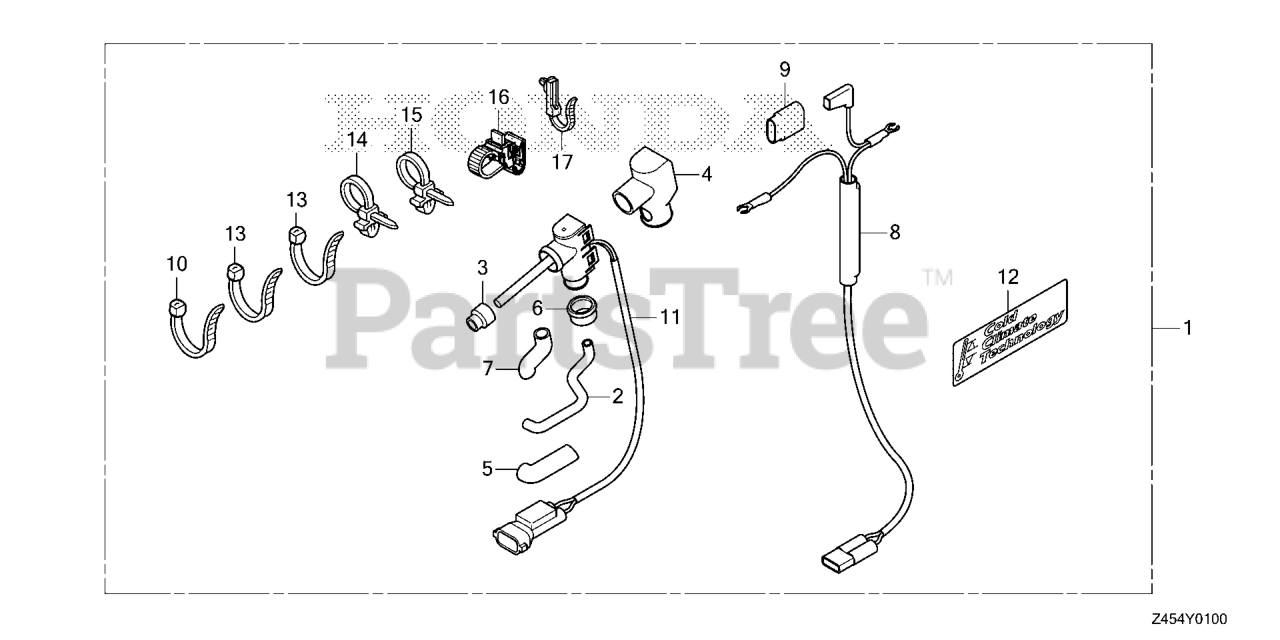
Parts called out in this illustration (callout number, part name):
1	KIT, BREATHER HEATER
2	TUBE, BREATHER
3	TUBE B, BREATHER
4	INSULATOR
5	INSULATOR A
6	TUBE C, BREATHER
7	INSULATOR B
8	SUB-WIRE ASSY.
9	TUBE, PVC (16X30)
10	TIE, CABLE (C)
11	HEATER, BREATHER L
12	MARK (CCT)
13	BAND, WIRE HARNESS
14	BAND, WIRE HARNESS (150MM) (Honda Code 1352103). (BLUE)
15	CLIP, HARNESS BAND (145MM) (BLACK)
16	CLIP, HARNESS BAND (140.3MM) (BLACK)
17	BAND, HARNESS OFFSET (10) (122.5MM) (BLUE)(W/SEAL)
